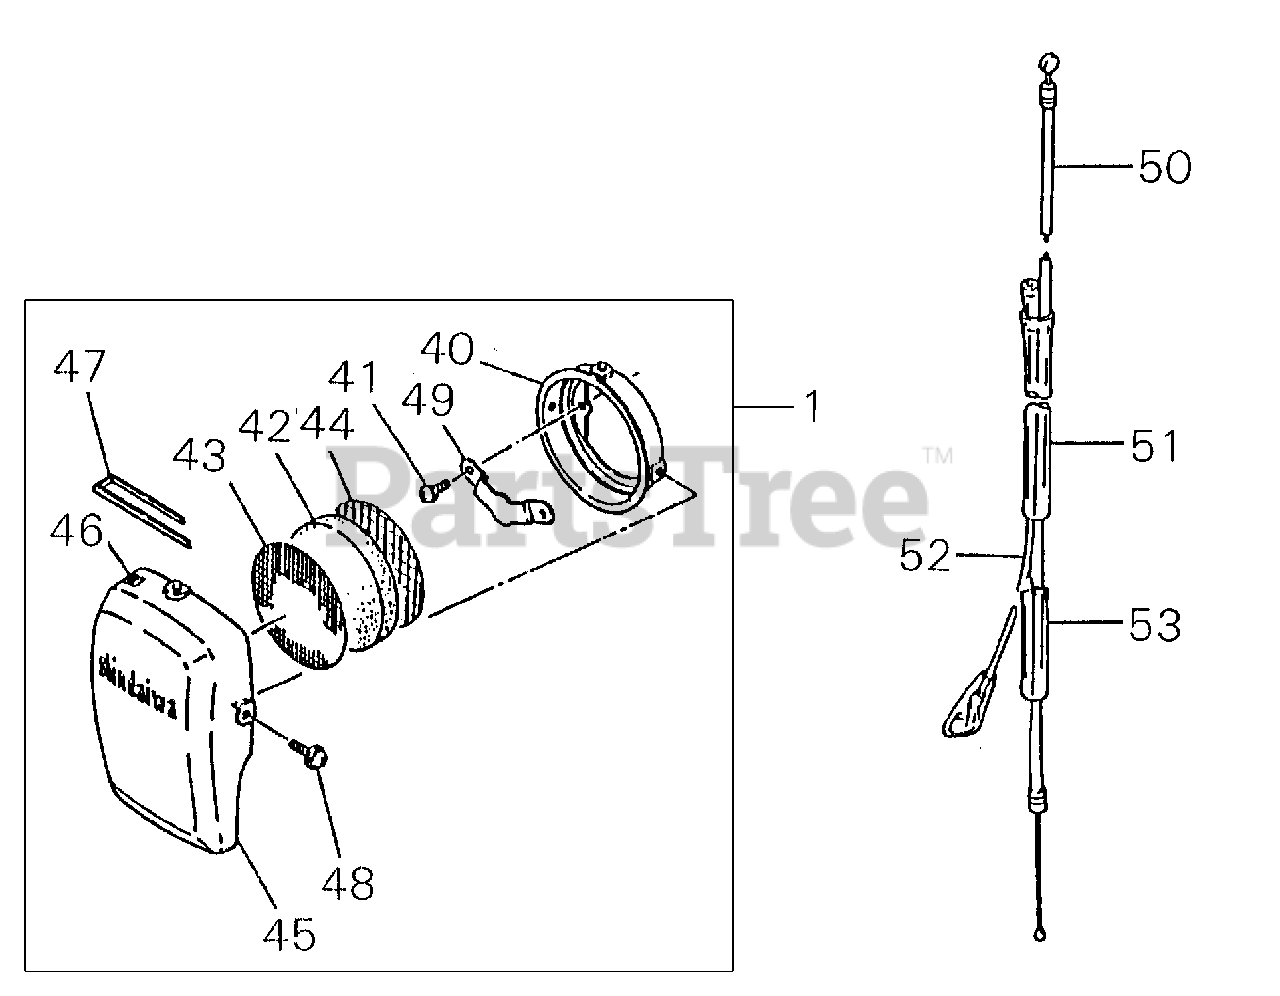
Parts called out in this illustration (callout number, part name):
1	AIR CLEANER KIT
40	CASE, AIR FILTER
41	SCREW
42	FILTER, AIR - FOAM
43	SCREEN - OUTER
44	SCREEN - INNER
45	COVER, AIR FILTER
46	LABEL - CHOKE
47	CLIP
48	SCREW
50	CABLE, THROTTLE
51	TUBE, PROTECTIVE
52	LEAD - GROUND
53	TUBE, PROTECTIVE
